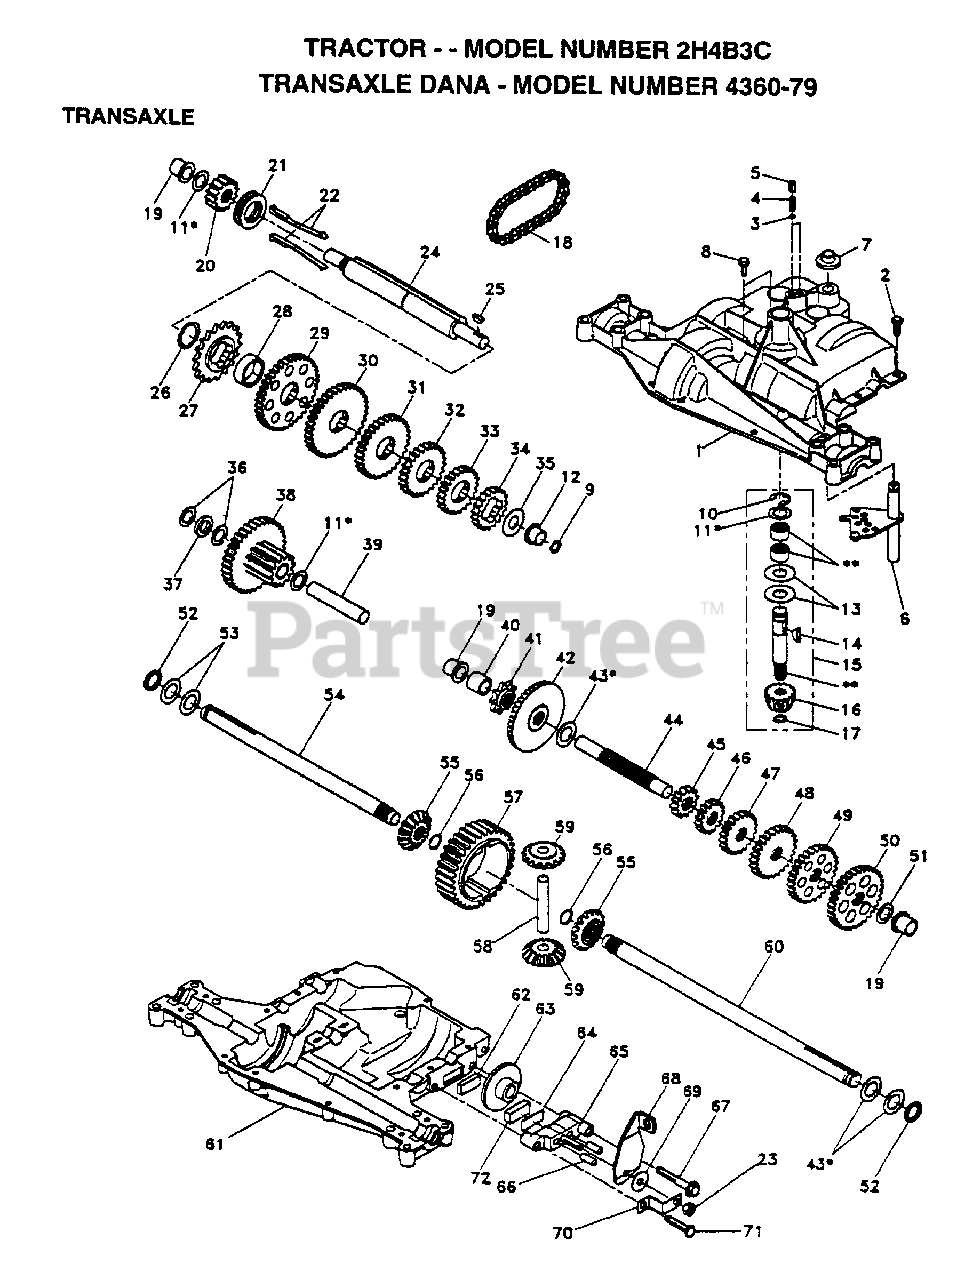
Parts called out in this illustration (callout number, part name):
1	HOUSING UPPER TRN
4	"SPRING, DETENT LT"
5	"SCREW, SET LT"
6	KIT SHIFTER ASM
7	SHIFTER BOOT
8	SCREW TAP W/SEAL
9	SQUARE RING
11	ASM KIT SHIM 4689
12	BEARING FLAN-DANA
13	WASHER T
14	KEY WOODRUFF-DANA
15	AS KIT INPUT SHFT
16	PINION 14T T
17	"RING,RETAINING LT"
18	"CHAIN,24 PTCH LT"
19	BEARING.FLNG.5510
20	GEAR SPUR 14 TTH
21	COLLAR CLUTCH
22	ASM KIT CLTCH KEY
23	NUT.LOCK.5/16-24
24	SHAFT INTERM DANA
25	WOODRUFF KEY
26	"RING,RETAINING LT"
27	SPROCKET 18T T
28	SPACER YT
29	GEAR SPUR 37 TTH
30	GEAR SPUR 35 TTH
32	GEAR 25T LT
33	GEAR SPUR 22 TT
34	SPUR GEAR 19T
35	"WASHER, PLAIN LT"
36	WASHER 025
37	SPACER
38	ASSM GEAR COMB
39	SHAFT IDLER
40	SPACER T
41	SPROCKET 9T LT
43	ASM KIT SHIM
44	SHAFT T
45	GEAR SPUR 12 TTH
46	GEAR SPUR 15 TTH
48	"GEAR, SPUR 25T LT"
49	GEAR 28T T
50	"GEAR, SPUR 31T LT"
51	WASHER 060
52	NEOPRENE WASHER
53	WASHER 031
55	GEAR 15T T
56	"RING,RETAINING LT"
58	SHAFT T
59	GEAR 1ST T
61	HOUSING LOWER TNS
62	PUCK T
63	BRAKE DISC. T
64	SPACER LT
66	PIN T
69	WASHER LT
71	"SCREW, TAPPING LT"
72	PUCK T
